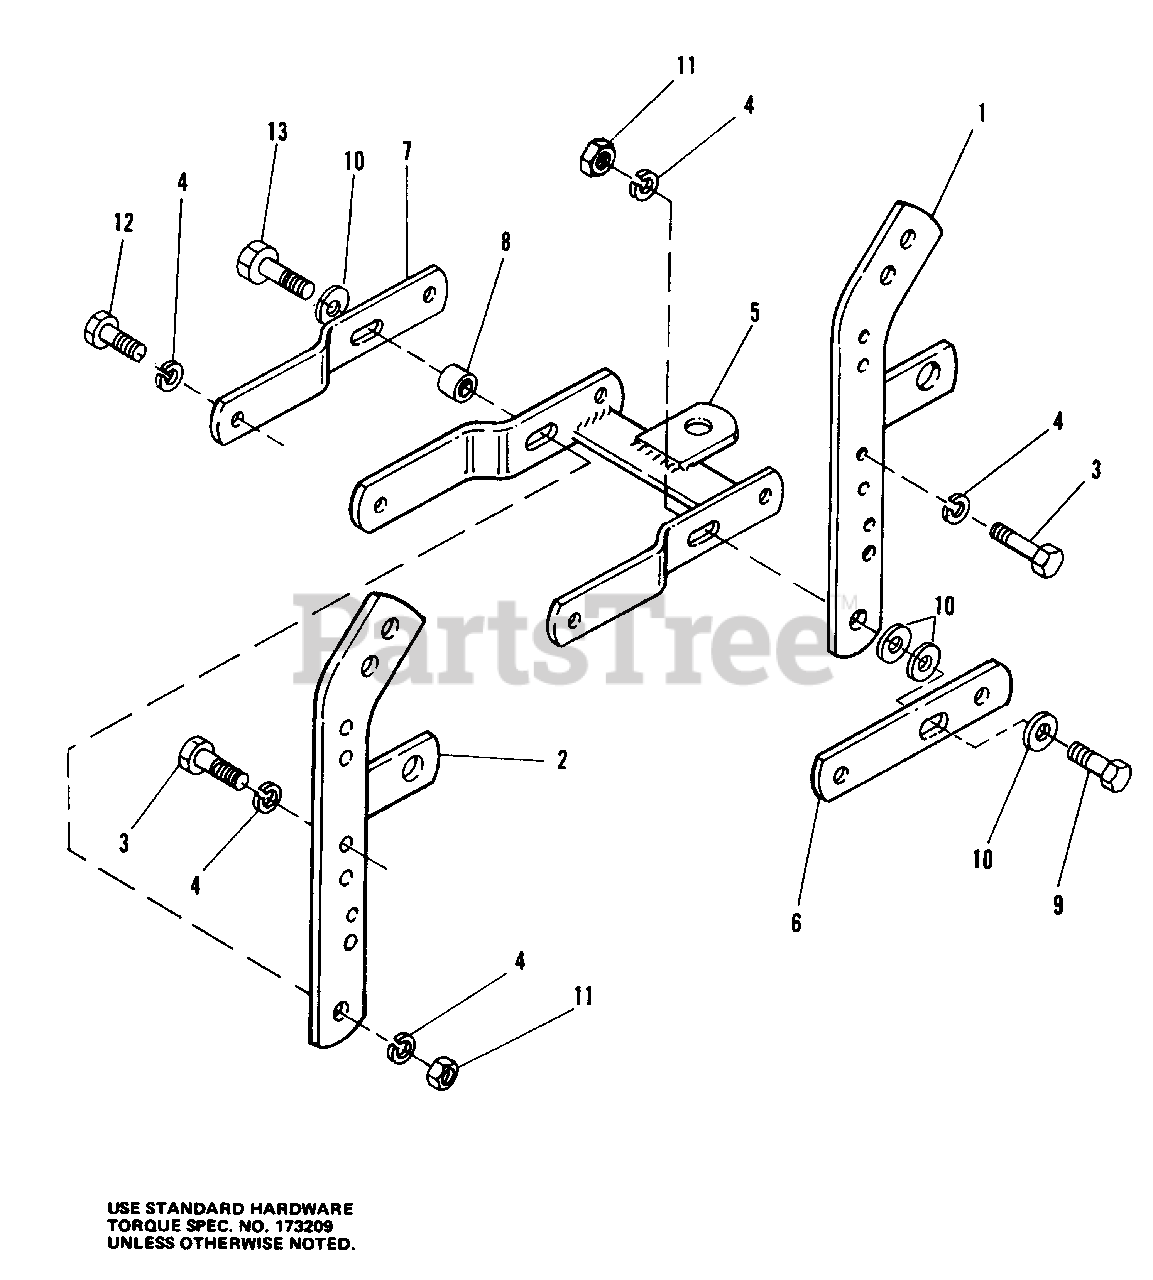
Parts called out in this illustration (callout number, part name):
1	L.H. ARM ASSEMBLY
2	R.H. ARM ASSEMBLY
3	CAPSCREW, Hex Hd., 7/16-14 x 1
4	LOCKWASHER, 7/16
5	DRAWBAR ASSEMBLY
6	BAR, Pull, L.H.
7	BAR, Draw, R.H.
9	CAPSCREW, Hex Hd., 7/16-14 x 1-1/2
10	WASHER, 7/16
11	NUT, Hex, 7/16-14
12	CAPSCREW, Hex Hd., 7/16-14 x 1-3/4
13	CAPSCREW, Hex Hd., 7/16-14 x 2-1/4
